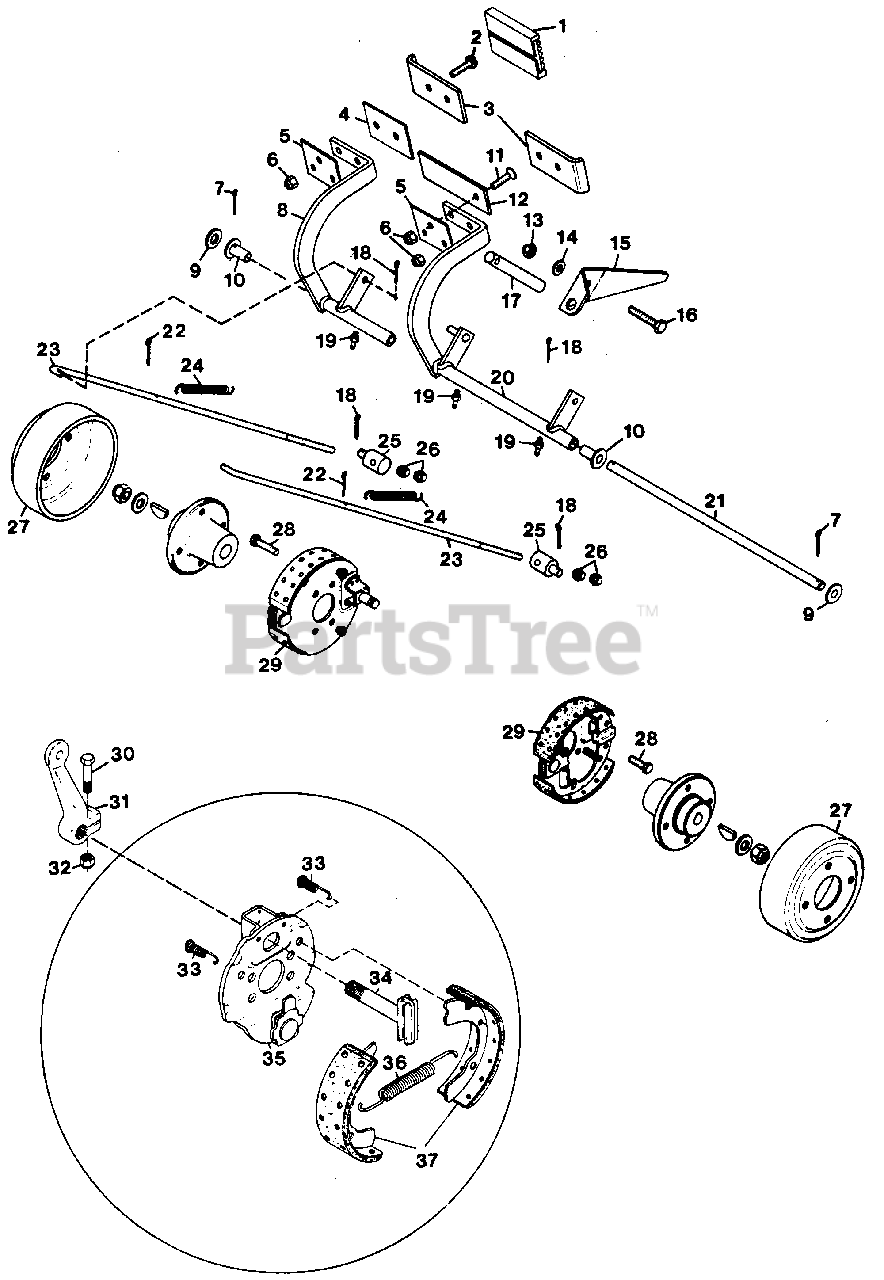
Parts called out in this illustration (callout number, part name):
1	Pad, Pedal
2	Bolt, Carriage 1/4-20x1.25
3	Pedal, Brake
4	Plate, Brake
5	Assembly, Brake Lock Plate
6	Nut, Lock 1/4-20
7	Pin, Cotter .125x1.25
8	Weldment, Brake Pedal
9	Washer, Flat .656x1.250x.100
10	Bearing
11	Screw, Machine 1/4-20x1.0
12	Assembly, Brake Lock Arm
13	Nut, Lock 3/8-16
14	Washer, Nylon .375x.75x.060
15	Lever, Brake Lock
16	Bolt, Hex 3/8-16x2.25
17	Rod
18	Pin, Cotter .09x.75
19	Fitting, Lube 1/4-28
20	Weldment, Brake Pedal
21	Shaft, Brake
22	Pin, Cotter .125x.75
23	Rod, Brake
24	Spring, Extension 5.5x.5x20 Rate
25	Pivot, Brake
26	Nut, Jam 3/8-24 Hex Hd
27	Drum, 7x1.75
28	Bolt, Hex 3/8-16x.75
29	Brake, 7x1.75 Mechanical
30	Bolt, Hex 5/16-18x1.25
31	Lever, Brake L.H.
31	Lever, Brake R.H.
32	Nut, Lock 5/16-18
33	Spring, Shoe Retaining
34	Cam, Brake
35	Plate, Back
36	Spring, Shoe Return
37	Shoe, Brake
